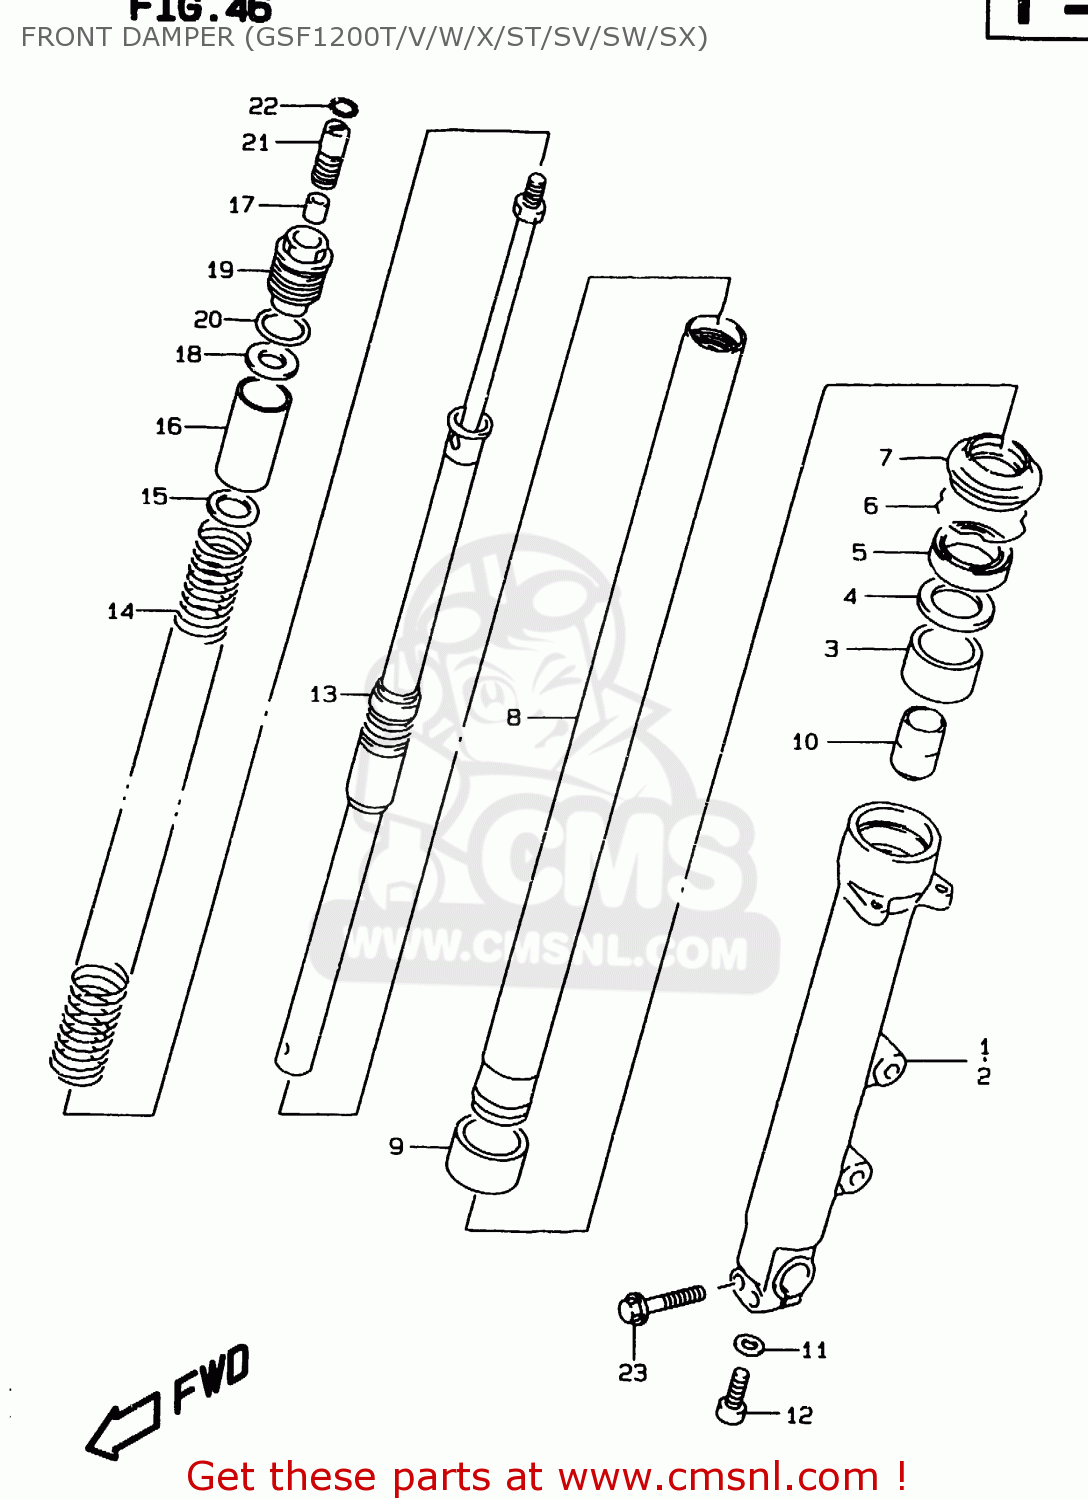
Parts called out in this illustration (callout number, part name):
1	TUBE,OUTER,RIGHT
2	TUBE,OUTER,L
3	BUSH,GUIDE
4	SPACER,SEAL
5	SEAL,OIL
6	CIRCLIP,FORK OIL SEAL
7	SEAL,DUST
8	TUBE,INNER
9	BUSH,SLIDE
10	PIECE,OIL LOCK
11	GASKET (NAS)
12	BOLT(8X27)
13	ROD,FR DAMPER
14	SPRING,FR
15	SEAT,SPRING LWR
16	COLLAR,SPRING(35X37X50)
17	NUT
18	SEAT,SPRING UPR
19	BOLT,FORK
20	O RING(D:2.5,ID:13.8)
21	ADJUSTER,SPRING
22	O RING(D:2.5,ID:13.8)
23	BOLT
